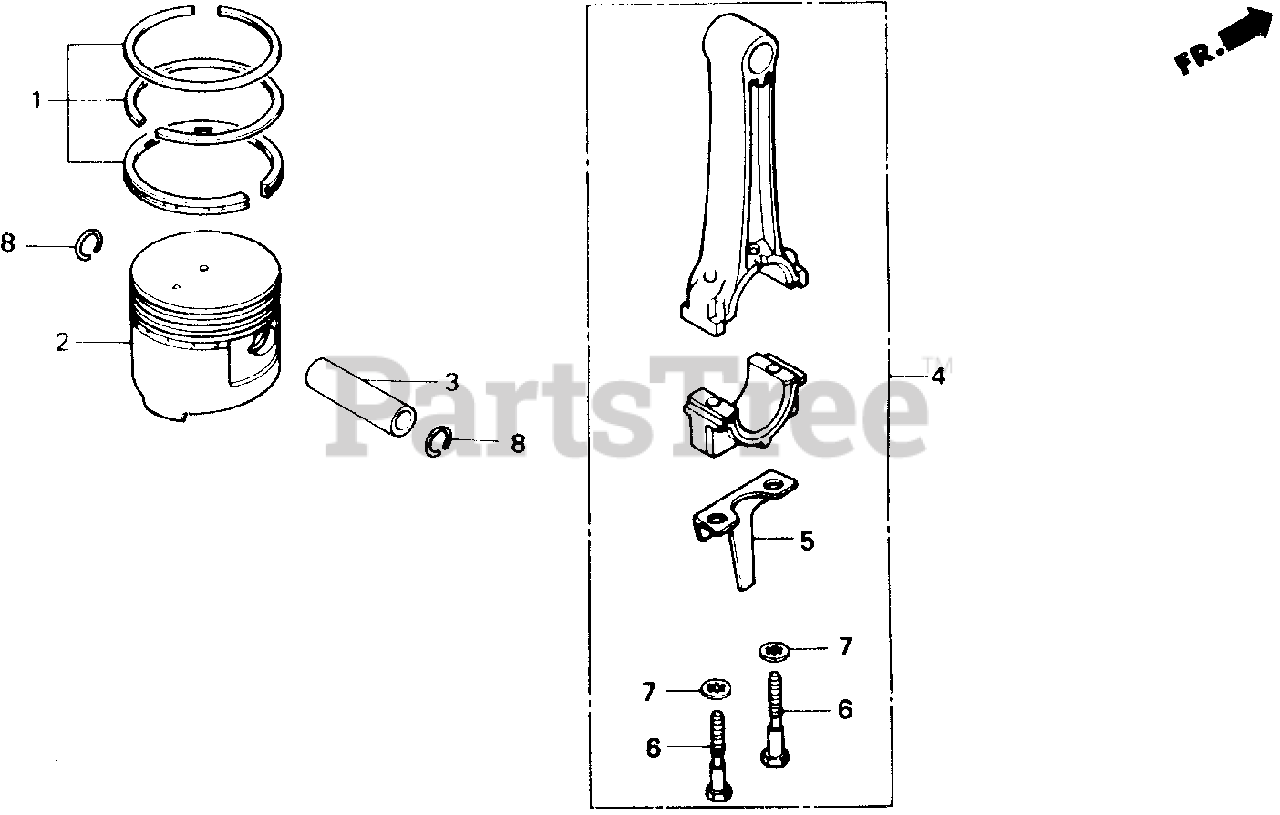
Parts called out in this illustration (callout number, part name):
1	RING SET, PISTON (STD) (NIPPON)
1	RING SET, PISTON (STD) (TEIKOKU)
1	RING SET, PISTON (0.25)
1	RING SET, PISTON (0.50)
1	RING SET, PISTON (0.75)
2	PISTON (STD)
2	PISTON (0.25)
2	PISTON (0.50)
2	PISTON (0.75)
3	PIN, PISTON
4	ROD ASSY., CONNECTING
5	DIPPER, CONNECTING ROD
6	BOLT, CONNECTING ROD (7MM)
7	WASHER, LOCK (7MM)
8	CLIP, PISTON PIN (15MM)
